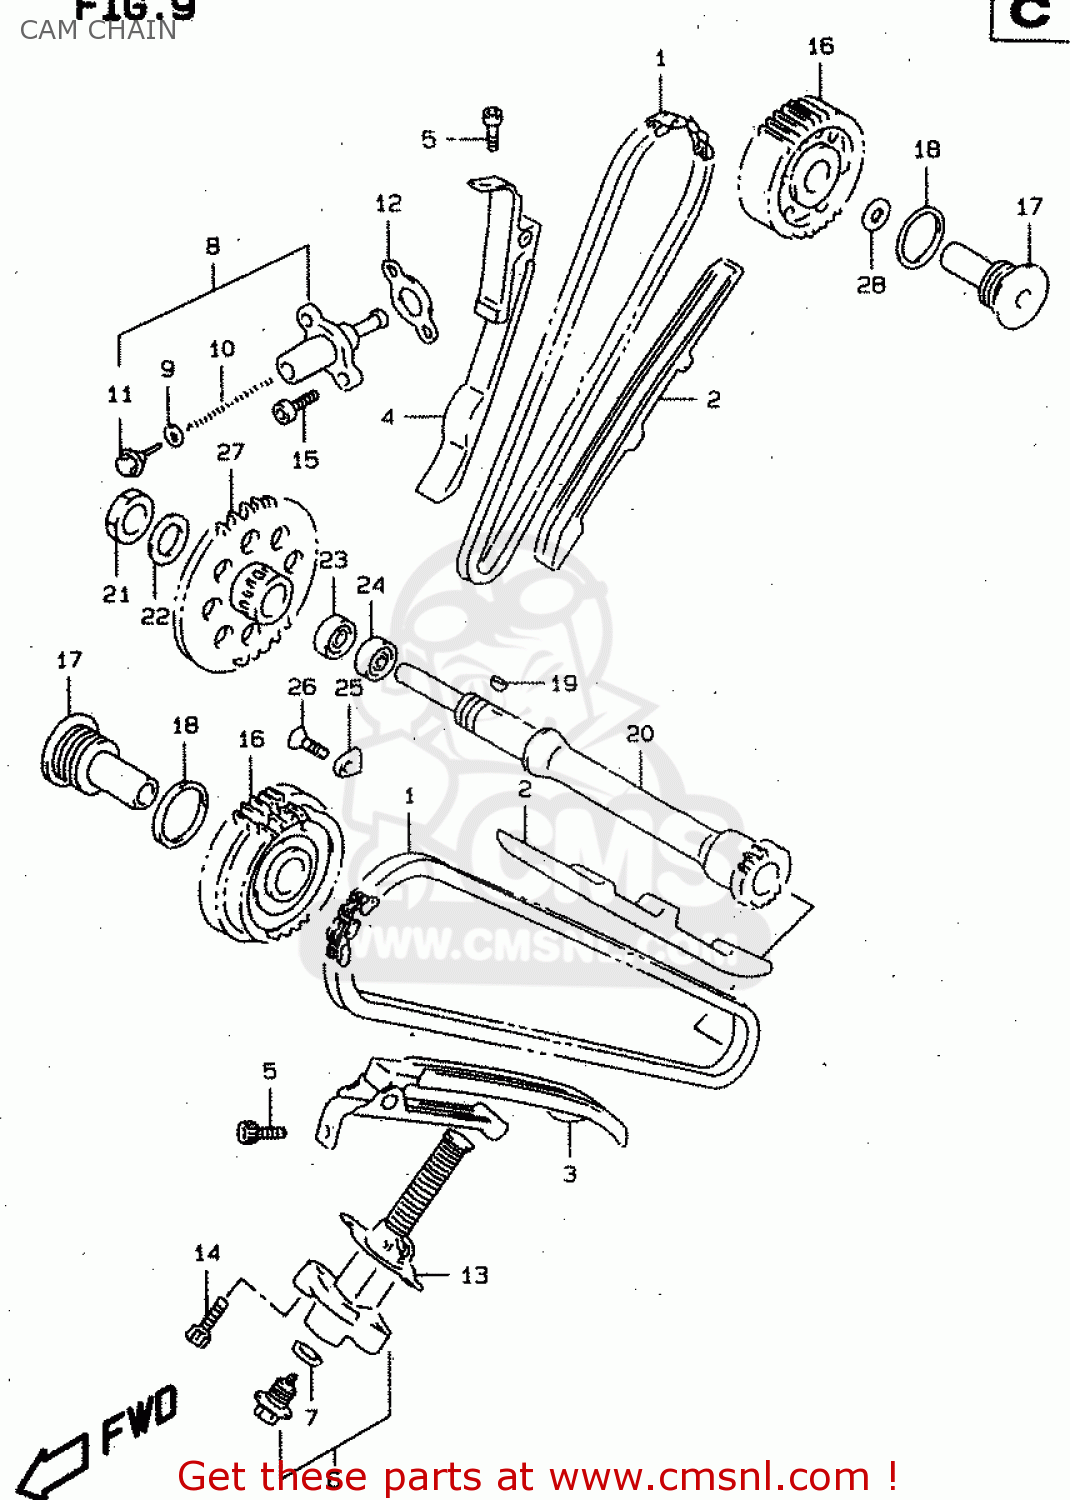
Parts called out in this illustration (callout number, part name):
1	CHAIN,CAMSHAFT DRIVE
2	GUIDE,CAM CHAIN
3	TENSIONER,CAM CHAIN FR
4	TENSIONER,CAM CHAIN RR
5	BOLT
6	ADJUSTER ASSY,RR TENSIONER
7	GASKET(12X21X2) (NAS)
8	ADJUSTER ASSY,TENSIONER
9	O RING
10	SPRING
11	PLUG,ADJUSTER
12	GASKET,TENSIONER ADJUSTER (NAS)
13	GASKET,TENSIONER ADJUSTER (NAS)
14	BOLT,CL.COVER
15	BOLT,CRKCASE,R
16	GEAR COMP,CAM CHAIN ID
17	SHAFT,IDLER NO.2
18	GASKET(26.5X30.5X1) (NAS)
19	KEY
20	SHAFT,IDLER
21	NUT
22	SHIM(16X26X1.5)
23	BEARING
24	BEARING
25	RETAINER,COUNTER BEARING,R
26	SCREW
27	SPROCKET,IDLER NO.1
28	SHIM(15X24X1)
